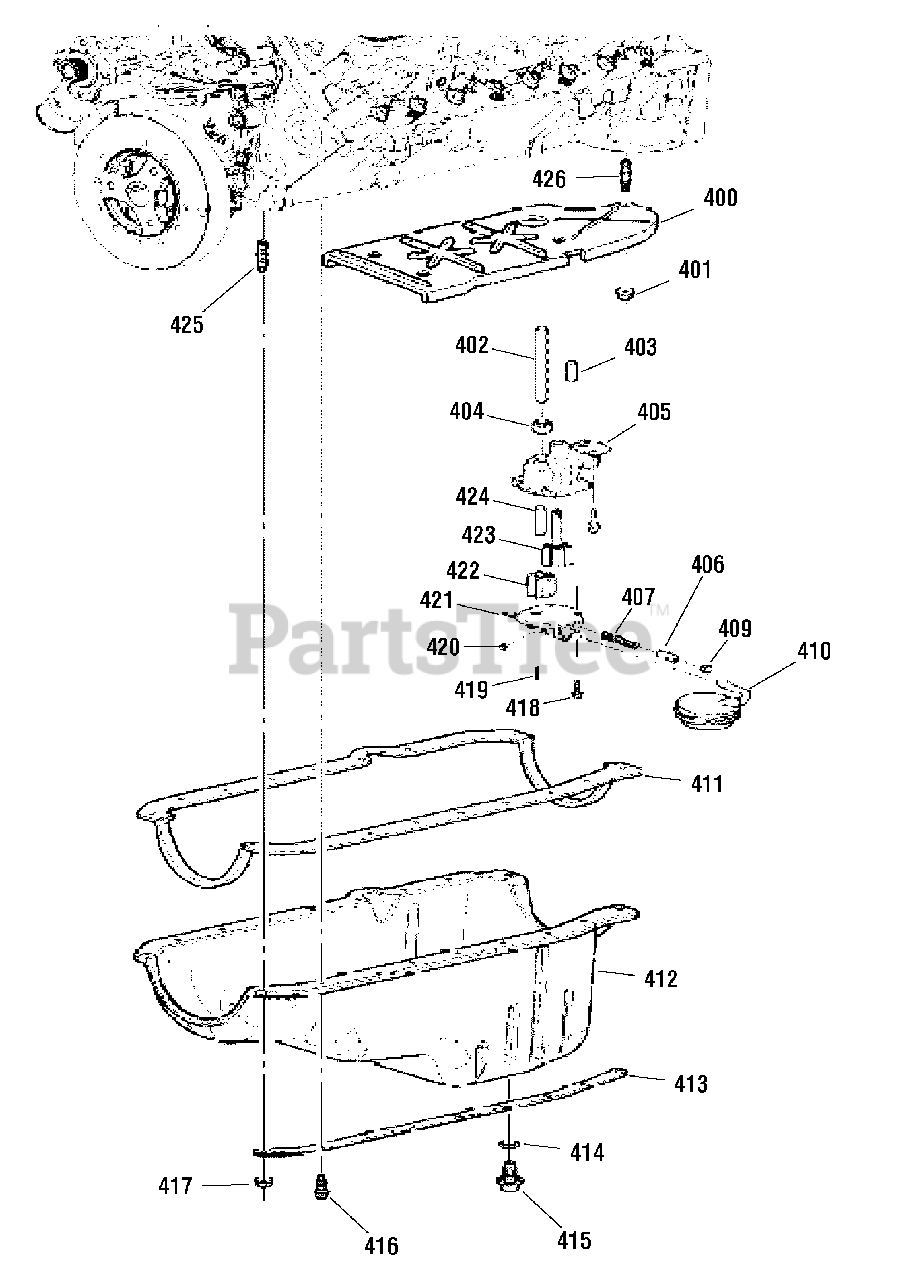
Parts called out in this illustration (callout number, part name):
400	* DEFLECTOR
401	* NUT
402	* SHAFT
403	* PIN
404	* RETAINER
406	* BOLT
407	* SPRING
409	* PLUG
412	* OIL PAN
413	* REINFORCEMENT
416	* BOLT
417	* NUT
418	* BOLT
419	* PIN
420	* PLUG
421	* COVER
422	* GEAR
423	* GEAR
424	* SHAFT
425	* STUD
426	* STUD
